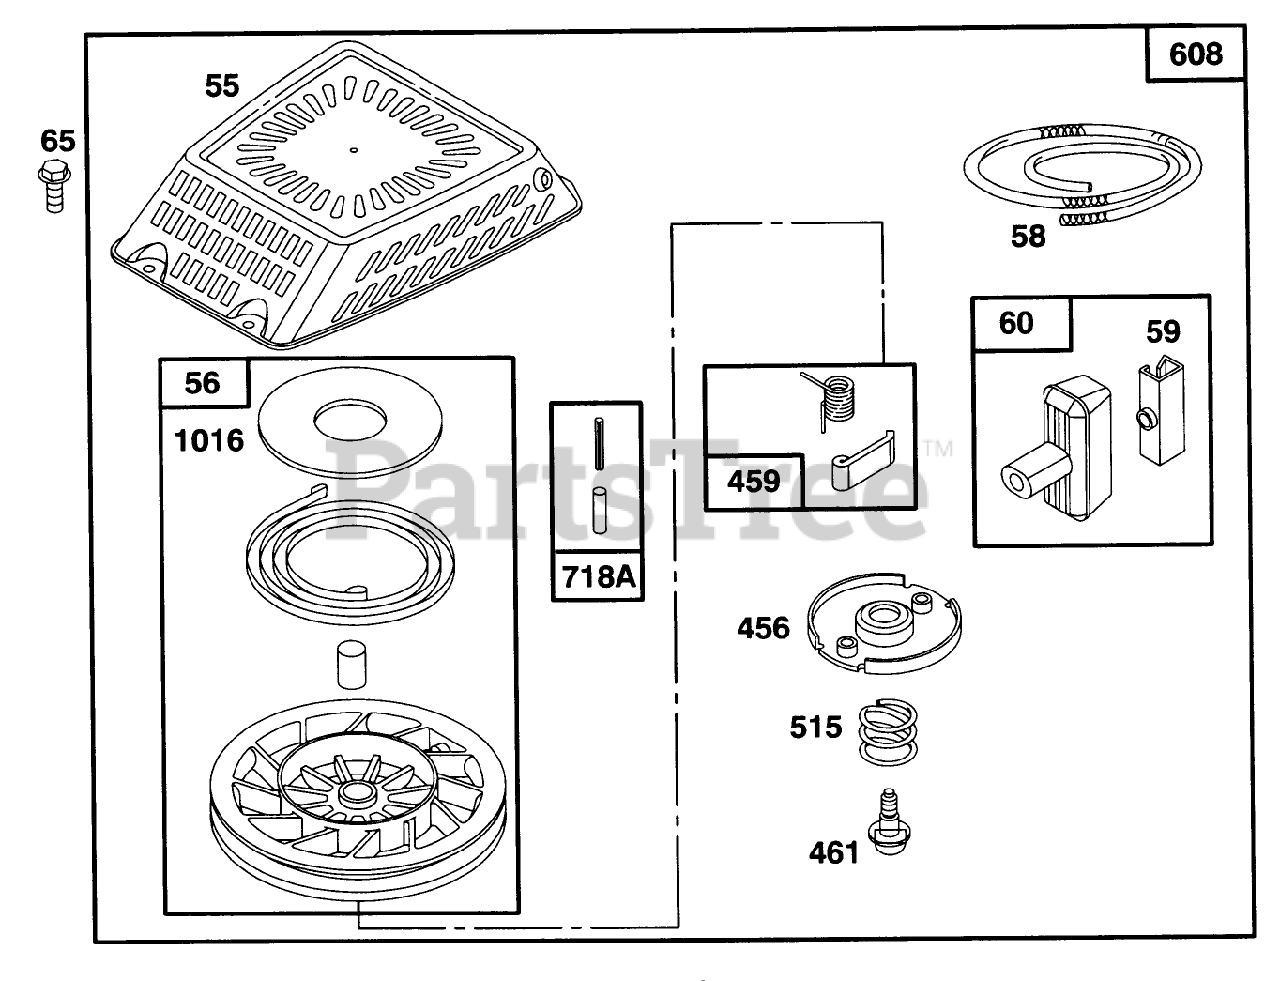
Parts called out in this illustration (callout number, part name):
59	INSERT-HANDLE, REWIND
456	RETAINER - SPRING
515	SPRING - RETAINER
